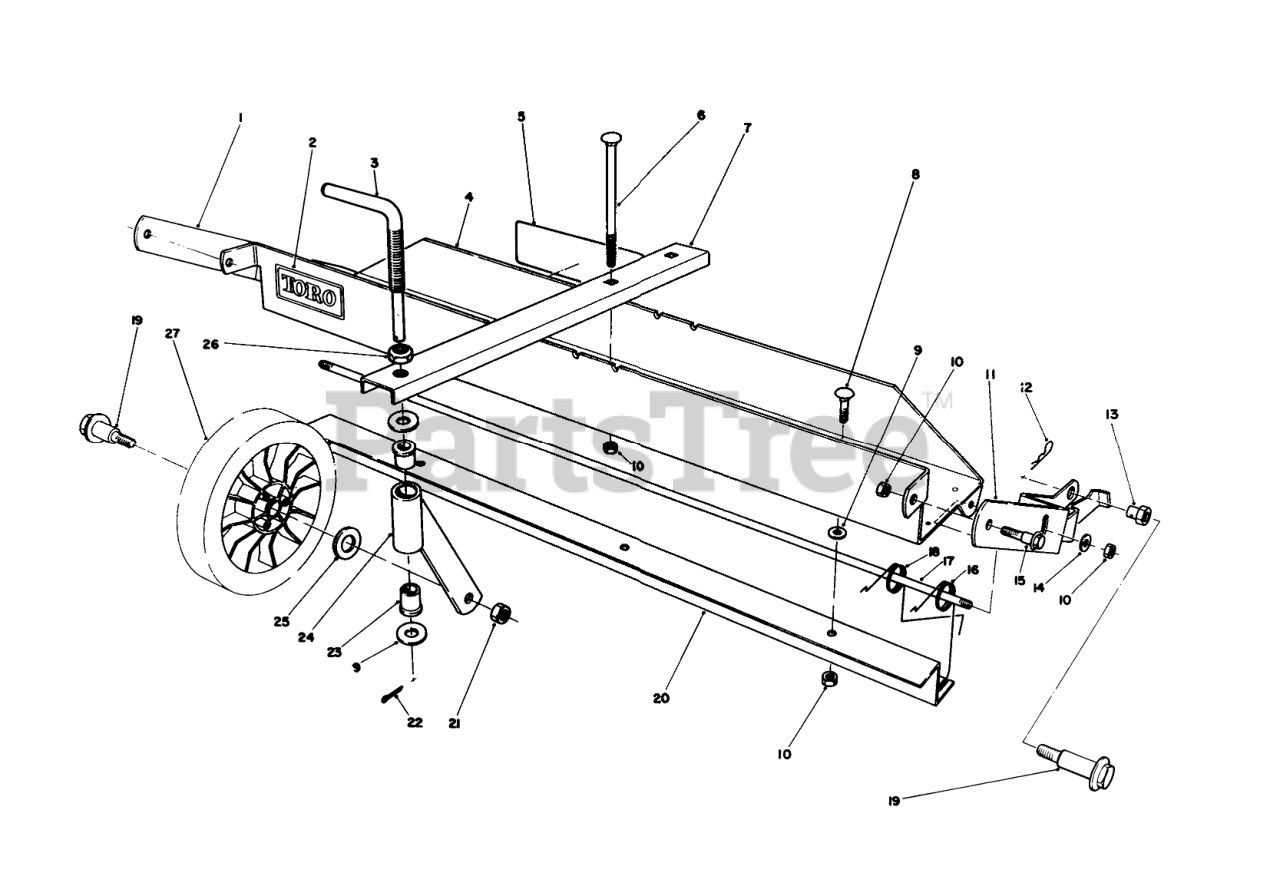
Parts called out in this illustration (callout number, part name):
1	Frame R.H.
2	Decal-Toro
3	CASTOR ADJ ROD
4	Frame-Main (Incl. Ref. #2)
5	Decal-Instruction
6	SCREW-CARR
7	Castor Frame
8	BOLT-CARR
9	WASHER-PLAIN
10	NUT-HEX, SIDE DEFORM
11	LH MTG FRAME
12	PIN-COTTER, HAIR
13	PIVOT NUT
14	WASHER-FLAT
15	BOLT-SHOULDER
16	DETHATCHER SPRING
17	SPRING SUPPORT ROD
18	DETHATCHER SPRING
19	BOLT-WHEEL
20	SPRING GUIDE STRAP
21	NUT-LOCK
22	PIN-COTTER
23	FLANGE BUSHING
24	Castor Tube & Support
25	WASHER
26	NUT-JAM
27	Wheel Assembly
